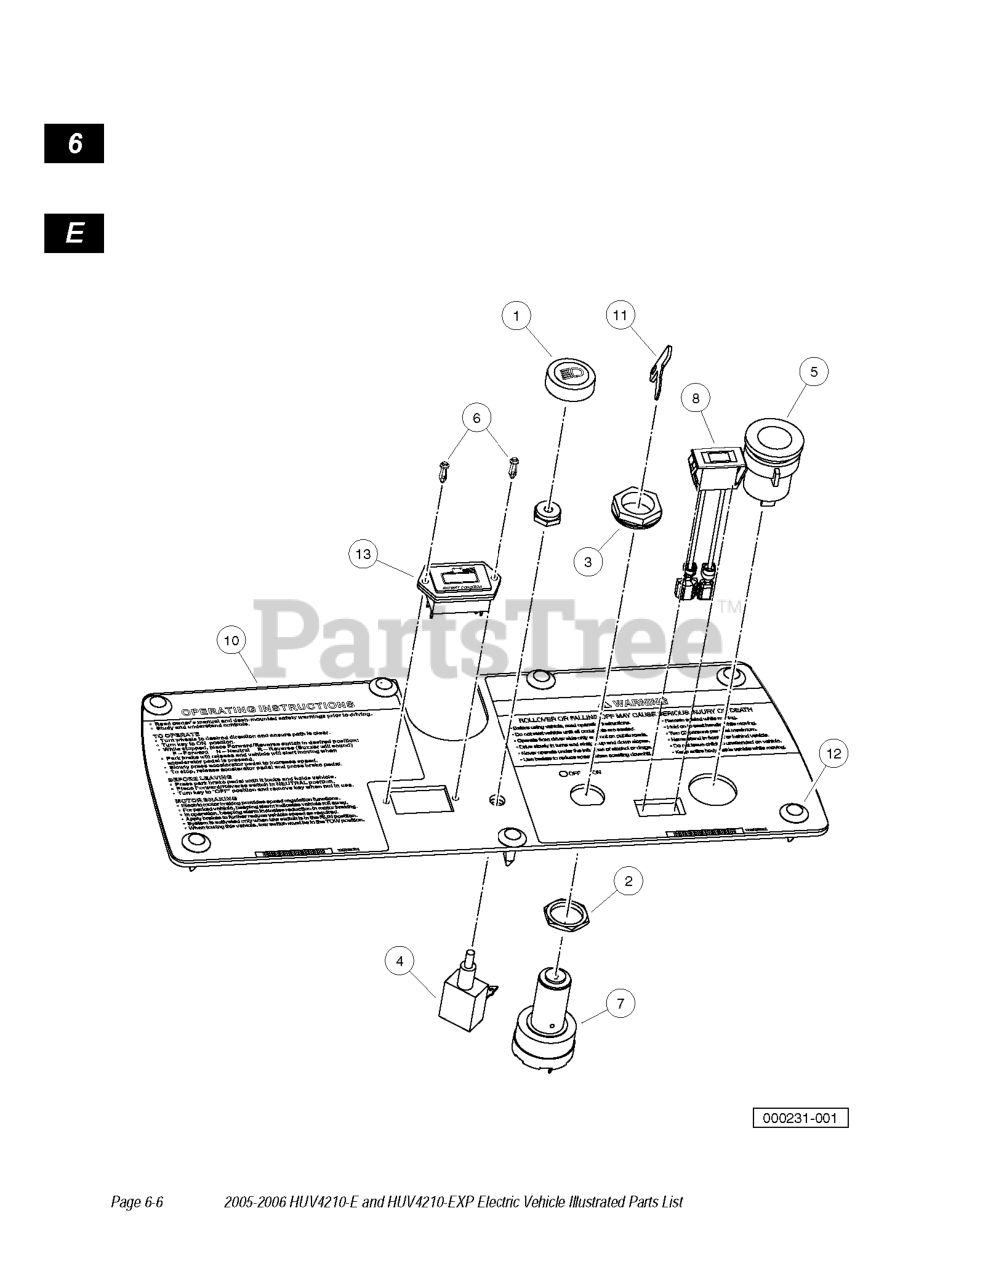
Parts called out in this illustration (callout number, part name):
1	LIGHT SWITCH KNOB
2	NUT, KEYSWITCH
3	NUT, KEYSWITCH
4	SWITCH, LIGHT
5	ACCESSORY RECEPTACLE
7	KEY SWITCH ELECT PREC
8	BATTERY LIGHT PREC
9	PANEL, INSTRUMENT, E
10	PANEL, INSTRMT, E W/12
11	KEY SET, OEM
12	SCREW, TUFLOK PANEL, 1/4
13	INDICATOR, BATT CHRG, 48V
